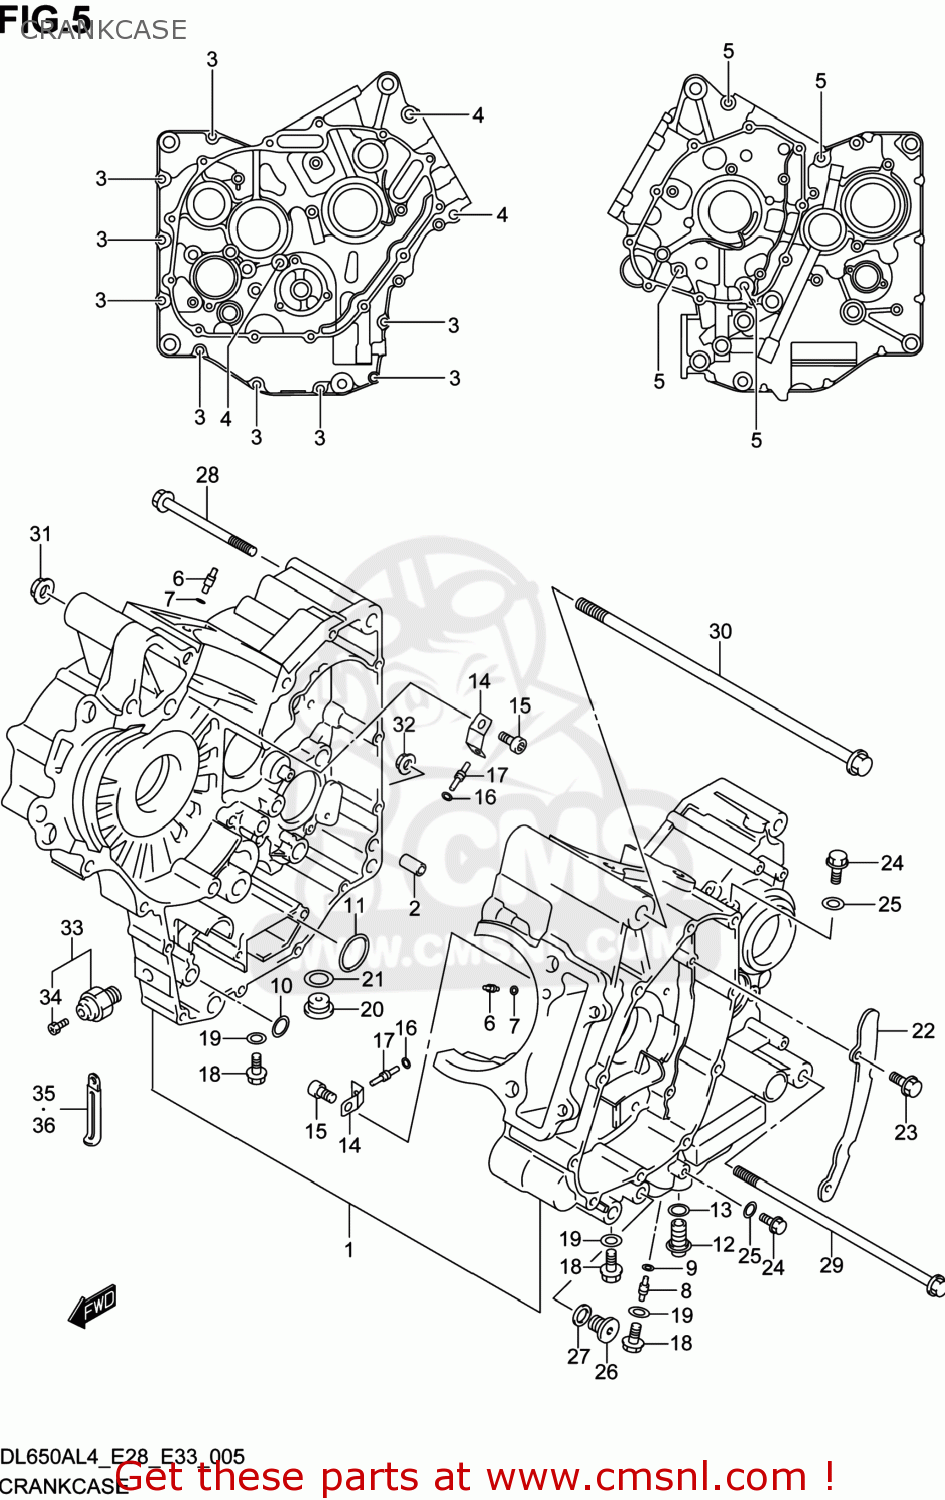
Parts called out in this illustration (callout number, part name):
1	CRANKCASE SET
2	PIN(8.4X11X20)
3	BOLT
4	BOLT
5	BOLT
6	JET,AIR(14)
7	O RING(D:1.2,ID:4)
8	JET,OIL GALLERY(18)
9	O RING(D:1.2,ID:4)
10	O RING(D:1.9,ID:12.6)
11	O RING(D:2.4,ID:15.8)
12	PLUG(12X20)
13	GASKET(12.1X16.2X3.7) (NAS)
14	PLATE,PISTON COOLING JET
15	BOLT(6X12)
16	O RING(D:1.2,ID:4)
17	JET(13)
18	BOLT
19	GASKET(8.2X14X1) (NAS)
20	PLUG,16X8
21	GASKET(16X22X2) (NAS)
22	PLATE,OIL SEPARATOR
23	BOLT
24	BOLT
25	GASKET(5.8X13X1.2) (NAS)
26	PLUG(12X10)
27	GASKET(12X17X1) (NAS)
28	BOLT(10X225)
29	BOLT(10X275)
30	BOLT(12X310)
31	NUT
32	NUT
33	SWITCH ASSY,OIL PRESSURE
34	BOLT,OIL PRESSURE SWITCH
35	CLAMP(L:45)
36	CLAMP(L:80)
